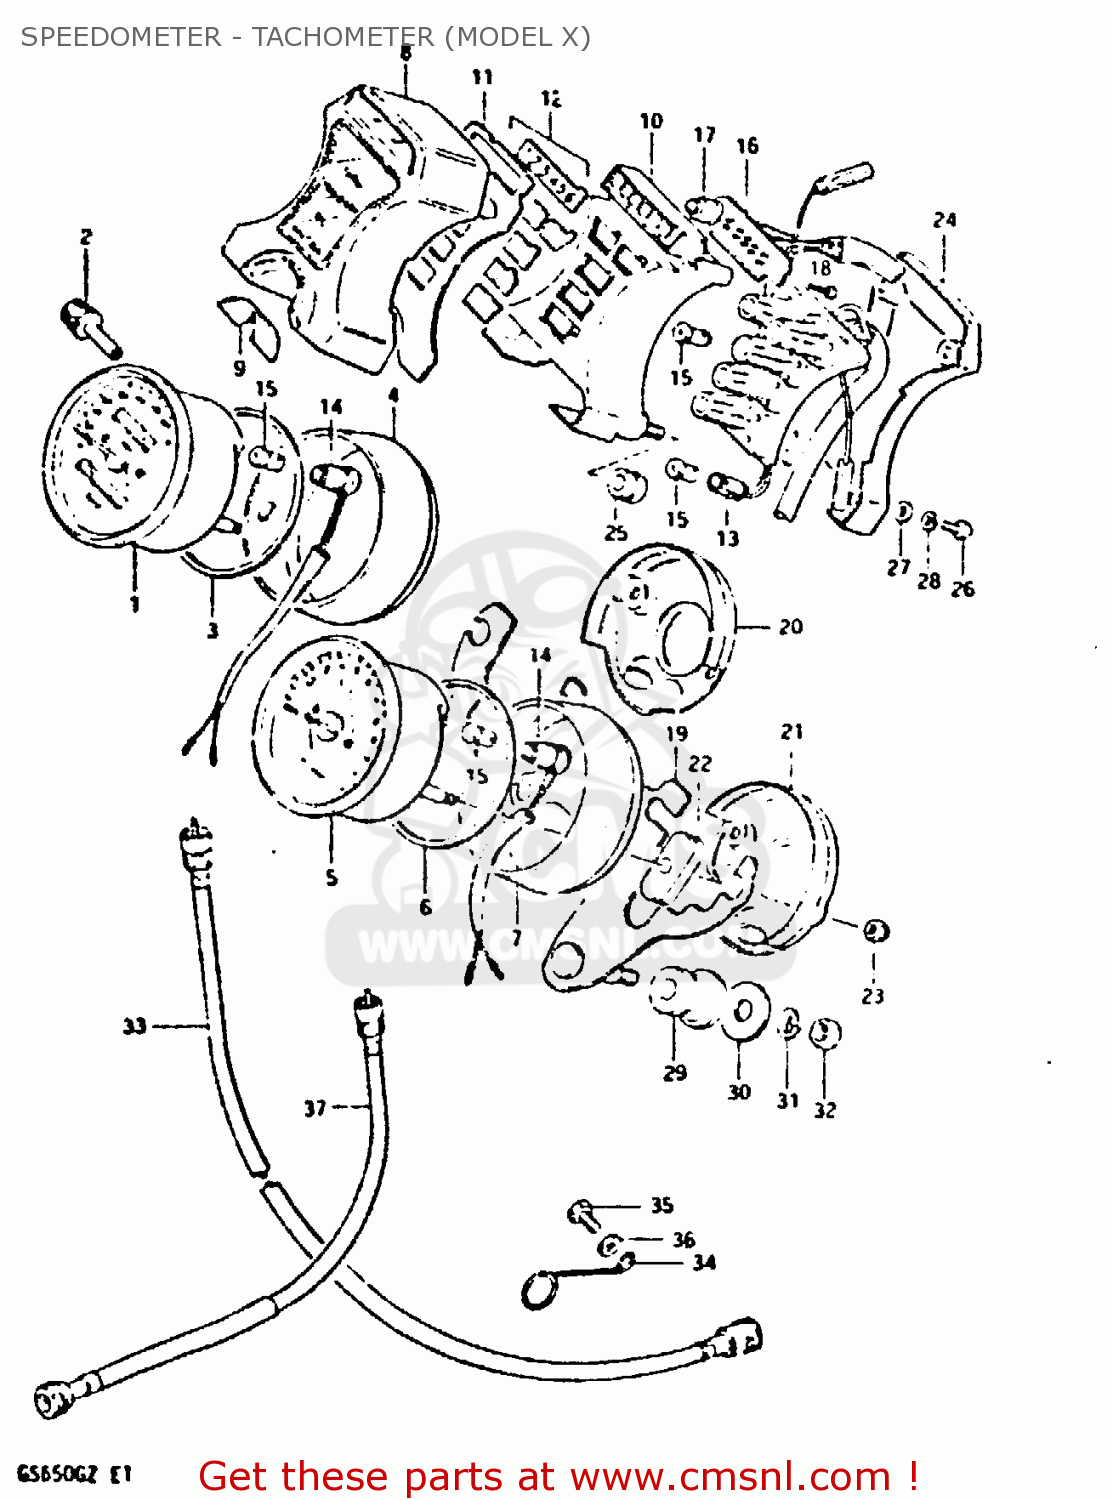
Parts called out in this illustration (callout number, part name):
1	SPEEDOMETER
2	KNOB,TRIP
3	CUSHION,SPEEDOMETER
4	COVER,SPEEDOMETER
5	METER,TACHOMETER
6	CUSHION,SPEEDOMETER
7	COVER,TACHOMETER
8	CASE,PILOT BULB
9	PAD
10	CASE,PILOT BULB,INNER
11	PLATE,PILOT BOX
12	LENS SET,PILOT LAMP
13	SOCKET
14	SOCKET,METER
15	BULB(12V3.4W,STANLEY,A72A)
16	SOCKET,GEAR INDICATOR
17	BULB(14V1.12W)
18	SCREW,GEAR INDICATOR
19	BRACKET,COMBINATION METER
20	COVER,SPEEDOMETER,UNDER
21	COVER,TACHOMETER,UNDER
22	CUSHION,METER
23	NUT
24	COVER,PILOT BOX,UNDER
25	CUSHION
26	SCREW
27	WASHER
28	LOCK WASHER
29	CUSHION,METER BRACKET
30	WASHER (8.5X29X1.6)
31	LOCK WASHER
32	NUT
33	CABLE ASSEMBLY,SPEEDOMETER
34	CLAMP,SPEEDOMETER CABLE
35	BOLT, UPPER
36	WASHER
37	CABLE ASSEMBLY,TACHOMETER
